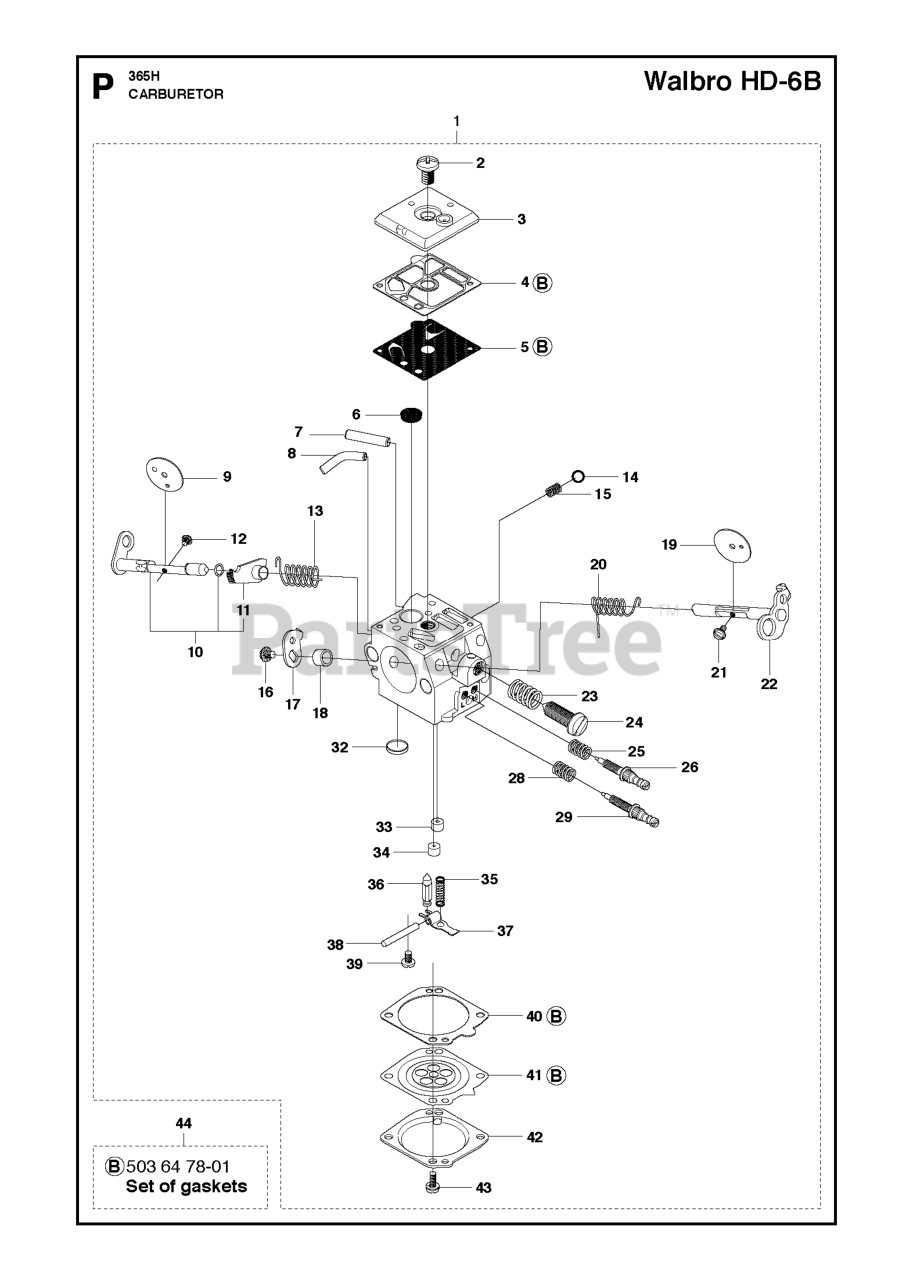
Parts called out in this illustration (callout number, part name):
1	CARBURETOR WALBRO HD-6B
4	GASKET, PUMP SIDE
5	PUMP DIAPHRAGM
6	FUEL INLET SCREEN
9	CHOKE FLAP
10	CHOKE SHAFT
19	THROTTLE FLAP
21	SCREW SHUTTERS
23	SPRING
26	SCREW
29	IDLING SCREW
32	WELCH PLUG
36	INLET NEEDLE
38	FULCRUM PIN
42	IMPULSE COVER
43	RP SCREW W/ WASHER
44	GASKET SET
